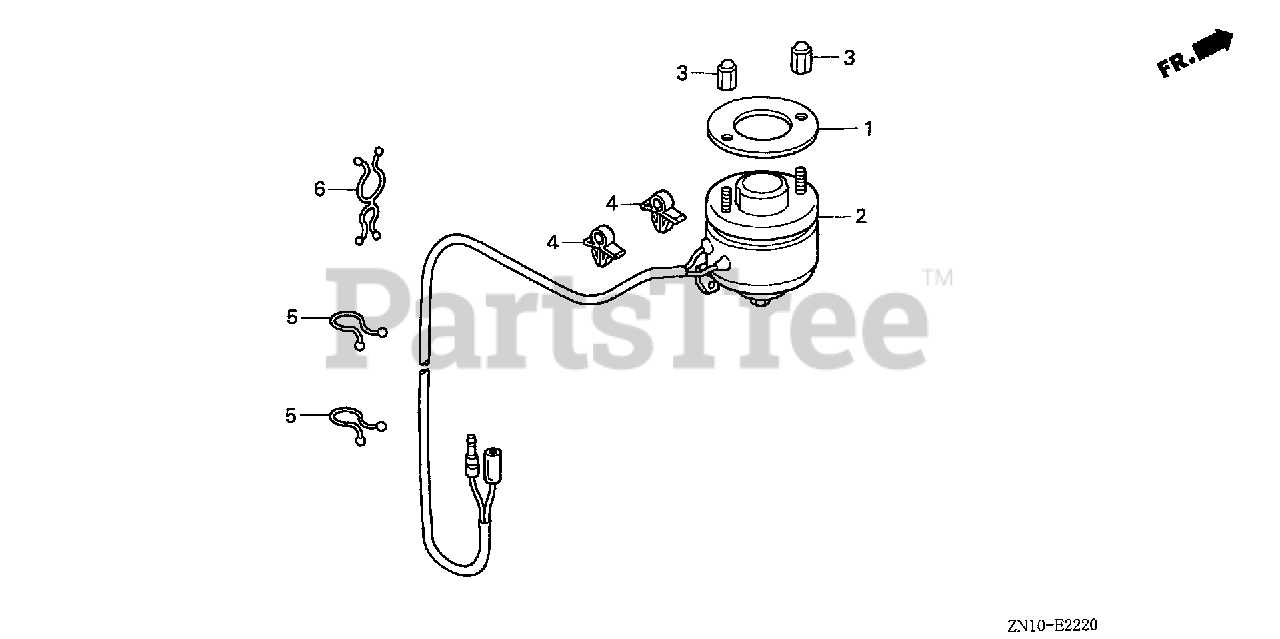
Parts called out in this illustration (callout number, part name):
1	PLATE, SOLENOID
2	SOLENOID ASSY., ROTARY
3	NUT, SPECIAL CAP
4	CLIP, WIRE HARNESS (6MM) (WHITE)
5	PURSE, LOCK (8MM)
6	CLIP, PURSE LOCK
